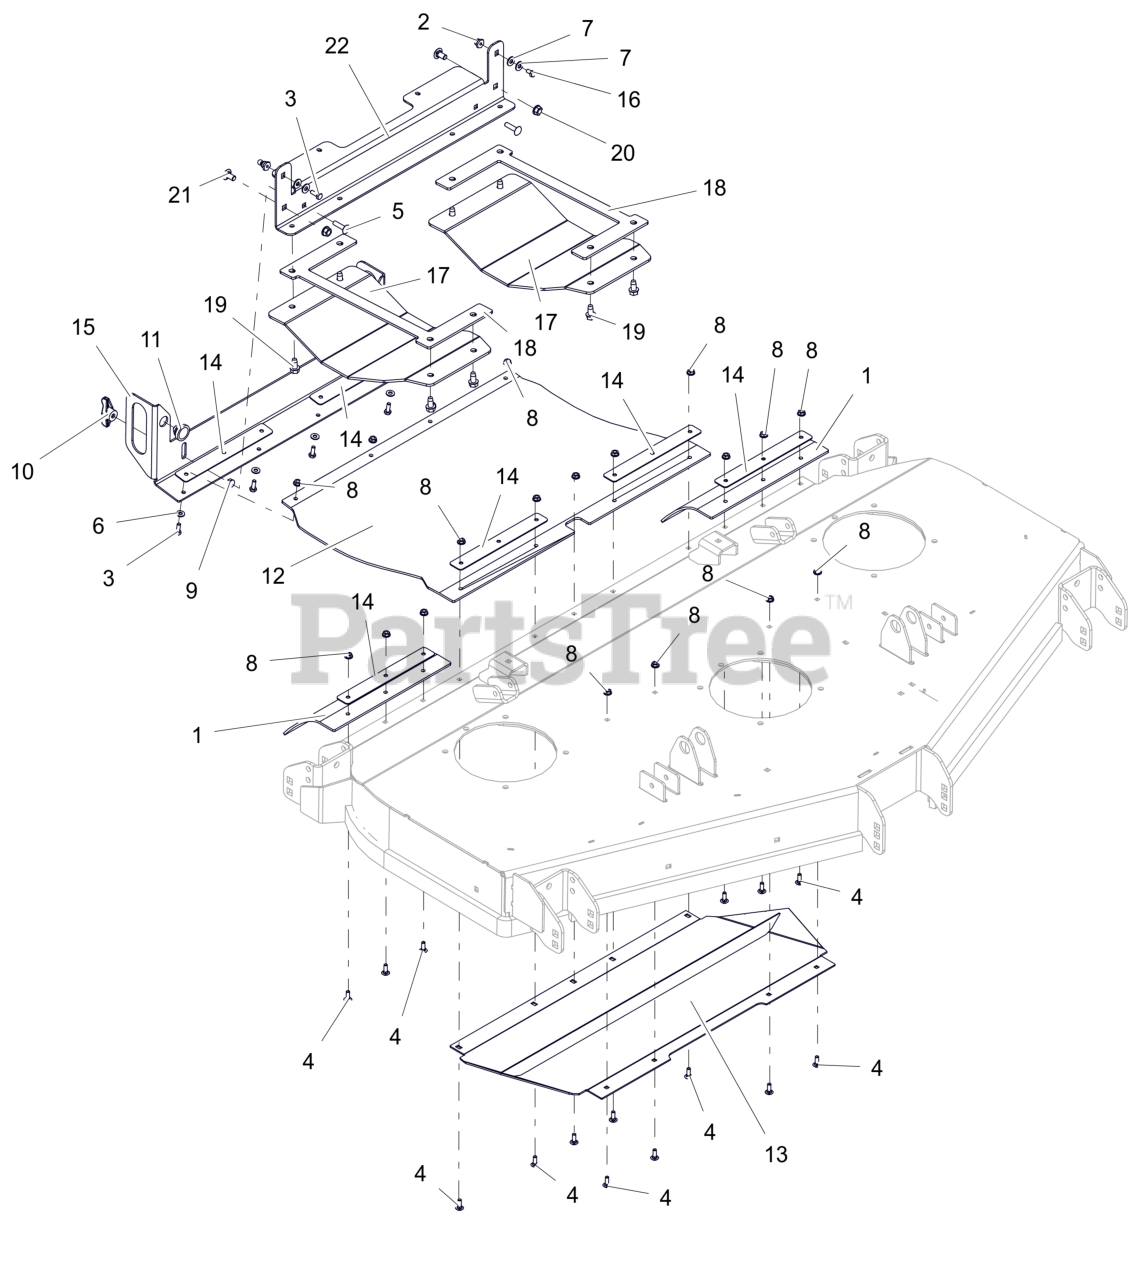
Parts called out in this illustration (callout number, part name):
1	FLAP- REAR DISCHARGE 60" TIRE
2	STUD, BALL FEMALE .250-20 THREAD
3	BLT, HEX .25-20X.75 G5 ZCC
4	BLT, RHSN .25-20X.750 G5 ZCC
5	BLT, RHSSN.31-18X1.25 G5 ZCC
6	WSHR,FLT .281X.625X.065 ZCC
7	WSHR, FLT .312X.734X.065 ZCC
8	NUT-LK-CTR-FLG .25-20 ZC120
9	NUT,LK-CTR-FLG .31-18 GF ZCC
10	KNOB,WING .31-18 UNC NYL/TALC
11	COUPLING, RUBBER PUSH-IN
12	CHUTE, REAR DISCHARGE
13	WLDMT, DEFLECTOR BAFFLE (ORANGE)
14	PLATE, CHUTE MTG (BLACK)
15	HANDLE, CHUTE MOUNTING (ORANGE)
16	BLT,HEX .25-20X.50 G5 ZCC
17	PLATE, SKID (BLACK)
18	PLATE, SKID TENSION (BLACK)
19	SCR,TAP .375-16X.75 HWH TR ZCC
20	NUT-LK-CTR-FLG .375-16 GF ZCC
21	BLT, RHSSN .38-16X.75 G5 ZCC
22	BRKT, SKID PLATE MTG. (ORANGE)
